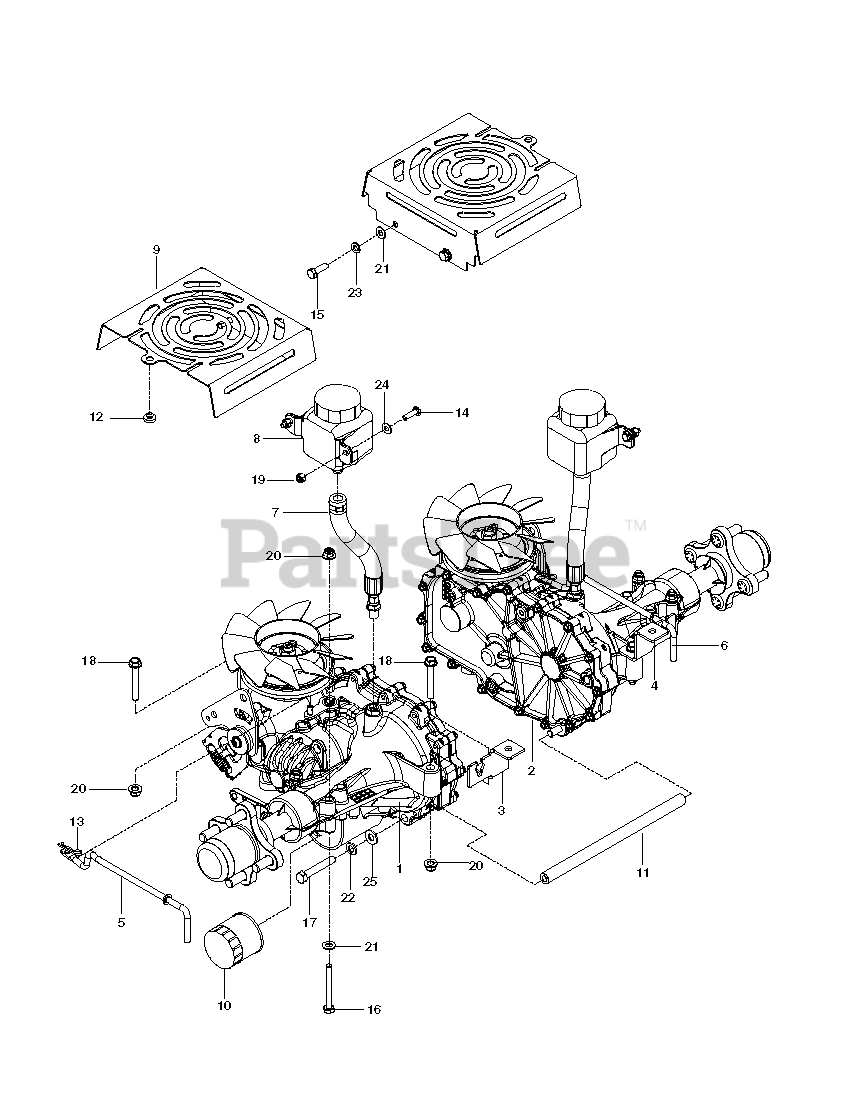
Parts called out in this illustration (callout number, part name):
1	HG_TRANS ZT-3100 LT
2	HG_TRANS ZT-3100 RT
3	BRACKET.TRANS.LT.BLACK
4	BRACKET, TRANS, RT BLACK
5	LINKAGE, LEFT BYPASS
6	LINKAGE, RIGHT BYPASS
7	HOSE ASSY, EXPANSION
8	TANK.EXPANSION.350ML 71328
9	SHIELD, FAN, BLK
10	HG_FILTER, ZT4800 52114
11	TUBE, SPACER, 3400
12	GROMMET, BUMPER
13	HAIRPIN #2
14	HCS 1/4-20X7/8 GR5
15	HCS 5/16C X 1
16	HCS 5/16C X 2-3/4
17	HCS 3/8-16X2-1/4 LOC PATCH GR8
18	HHFS 5/16-18 X 2.25 GD 5
19	NUT.1/4-20.HEX.NYLOC.ZD
20	5/16-18 NYLOC FLANGE NUT
21	FLAT WASHER 5/16 SAE
22	SLW 3/8 STD
23	WASHER.LOCK.HVY.HLCL.SPR.5/16
24	WASHER 1/4 SAE
25	WASHER 3/8 SAE FLAT
